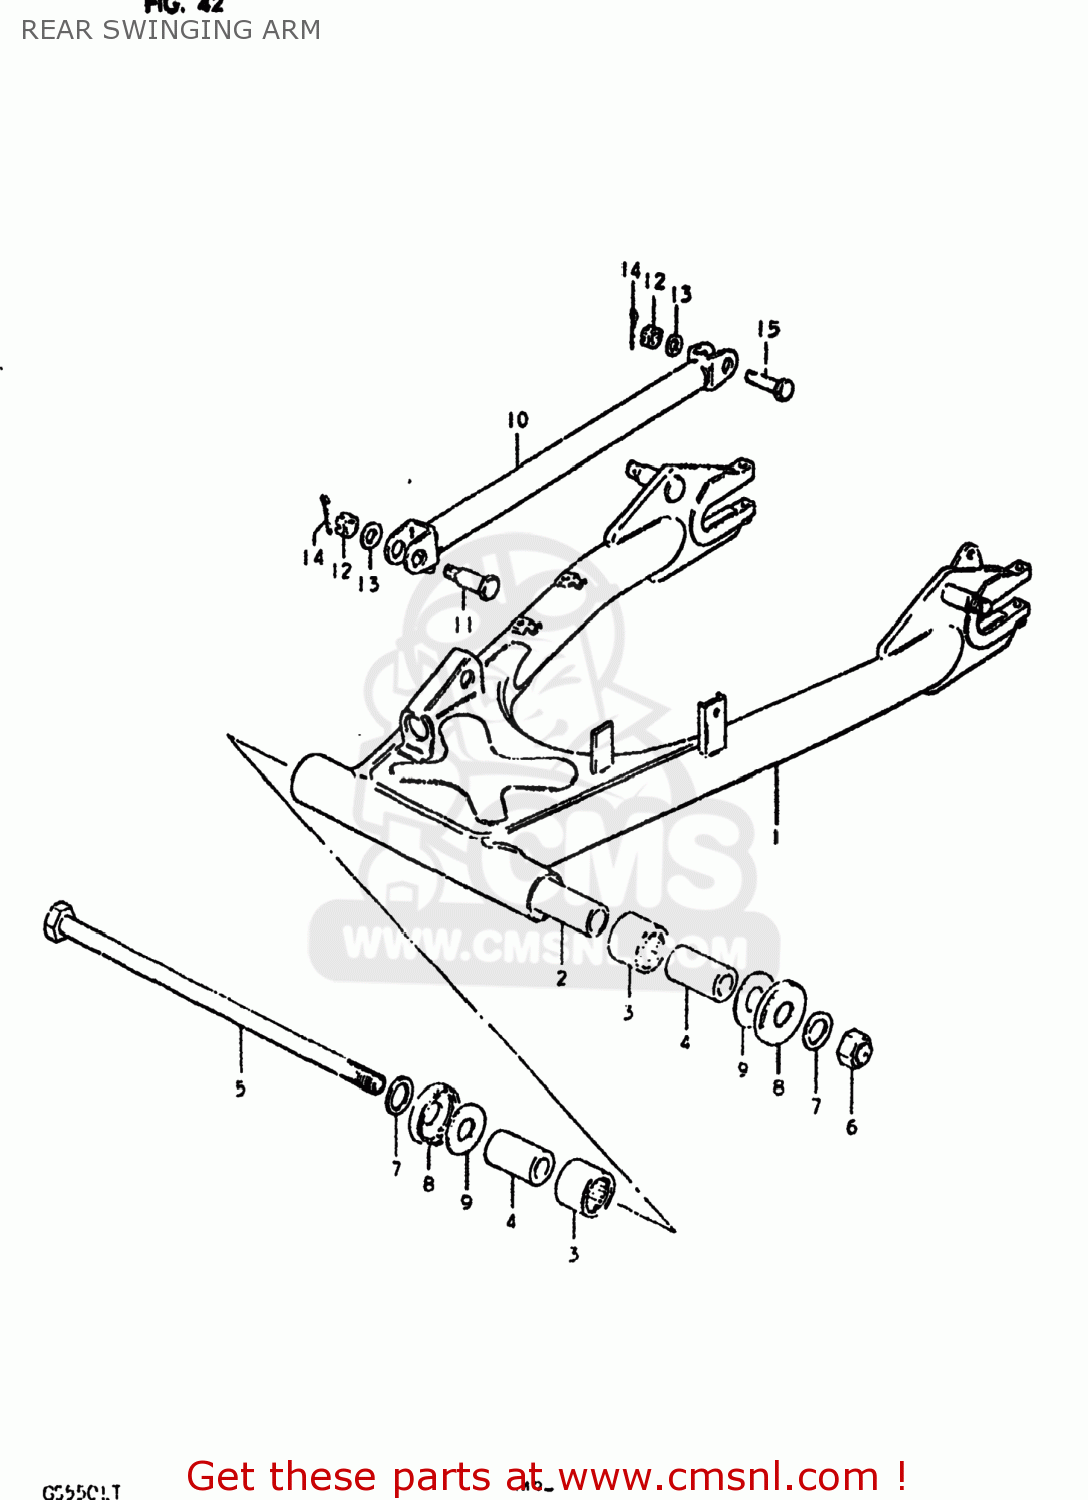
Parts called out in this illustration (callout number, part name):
1	SWING ARM ASSEMBLY,REAR
2	SPACER,RR SWGARM PIVOT CTR
3	BEARING(22X29X30)
4	SPACER,RR SWGARM PIVOT
5	SHAFT,REAR SWING ARM
6	NUT 14MM
7	WASHER
8	CVR,RR SWGARM DUST SEAL(OD:40)
9	WASHER(14.2X34X1)
10	LINK,REAR TORQUE
11	BOLT
12	NUT
13	WASHER
14	PIN 20X20
15	BOLT(10X39)
